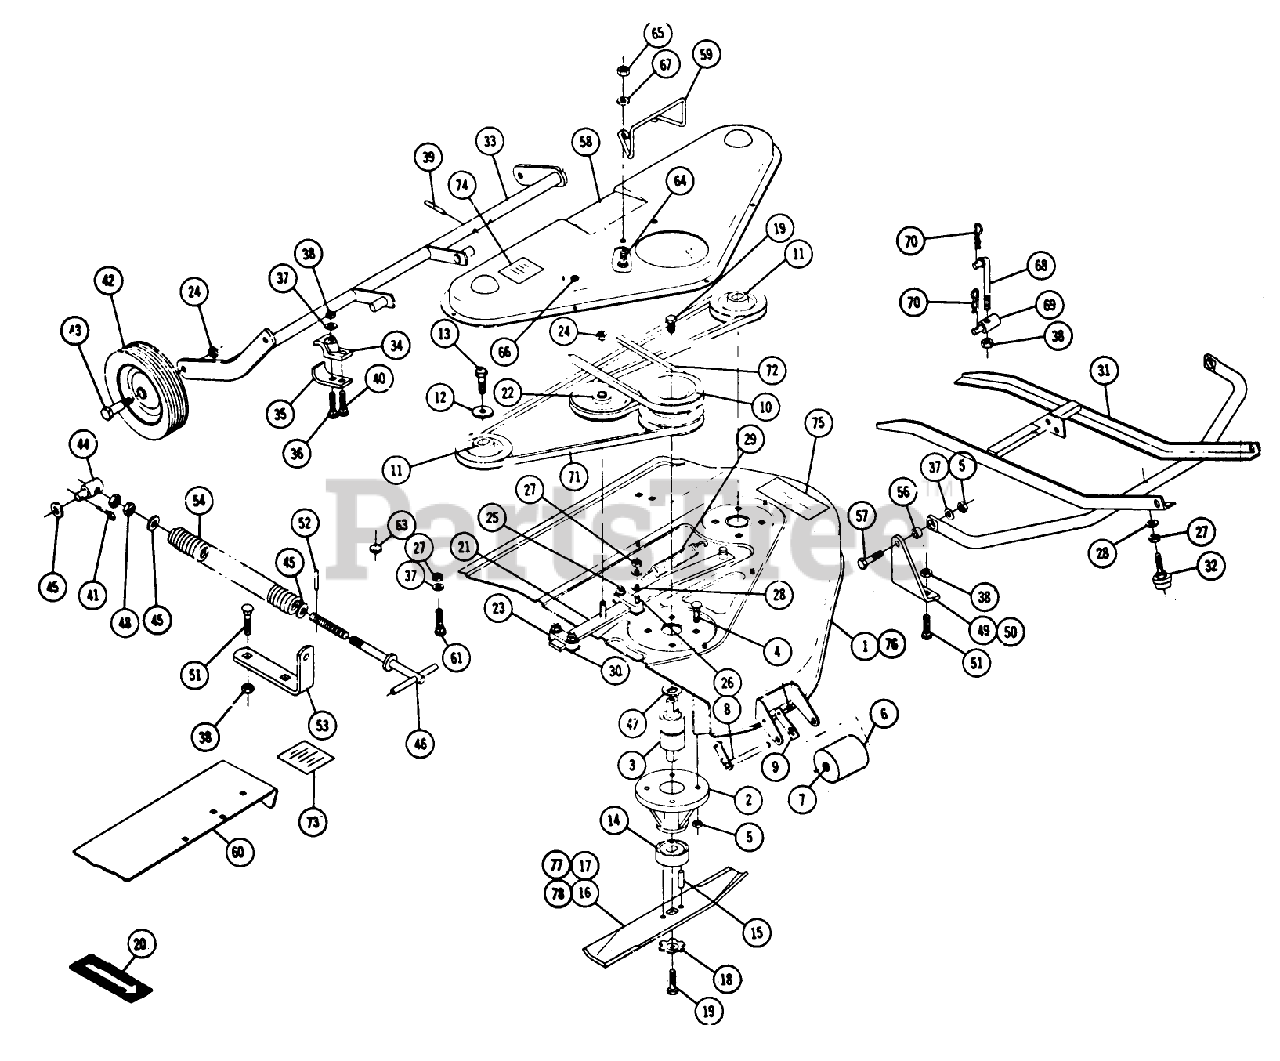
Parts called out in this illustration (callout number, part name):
1	Deck-Mower (Model 5-0610)
4	Bolt Carriage 3/8-16 x 1
12	WASHER
13	Bolt 3/8-16 x 3/4 Hex
14	CUP-SPINDLE
15	SPIROL ROLL PIN
19	Bolt 3/8-16 x 7/8
20	Decal Mower Width
21	Bar Idler Support
24	3/8-16 Jam Nut
25	Bolt-5/16-18 x 1/4
26	Bolt-5/16-18 x 1 1/2
27	Nut-Nylok
28	Washer
29	SPRING *R
32	Leveler-Mower
33	Height Control Bracket
34	DISCONTIUNUED
36	Bolt Carriage 3/8-16 x 2
37	Washer
38	3/8-16 E.S.
39	Roll Pin
40	Bolt Carriage 3/8-16 x 1
41	Hairpin
43	BOLT-SHOULDER
45	Washer
46	Crank
47	WASHER
48	Nut-1/2-13
49	Bracket L.H.
50	Bracket R.H.
51	Bolt 3/8-16 x 1
52	PIN-SPIROL
53	Bracket
54	Spring
57	Bolt 3/8-16 x 1
61	Bolt 5/16-18 x 5/8 Carriage
64	Screw 1/4-20 x 5/8
65	Nut, 1/4-20
66	HEX NUT 10-32 E.S. + + USE 3296-21 + +
67	Washer
68	Link-Lift
70	Hairpin
71	V-BELT
73	Decal-Height Adjustment
76	Deck-Mower (Model 5-0702)
